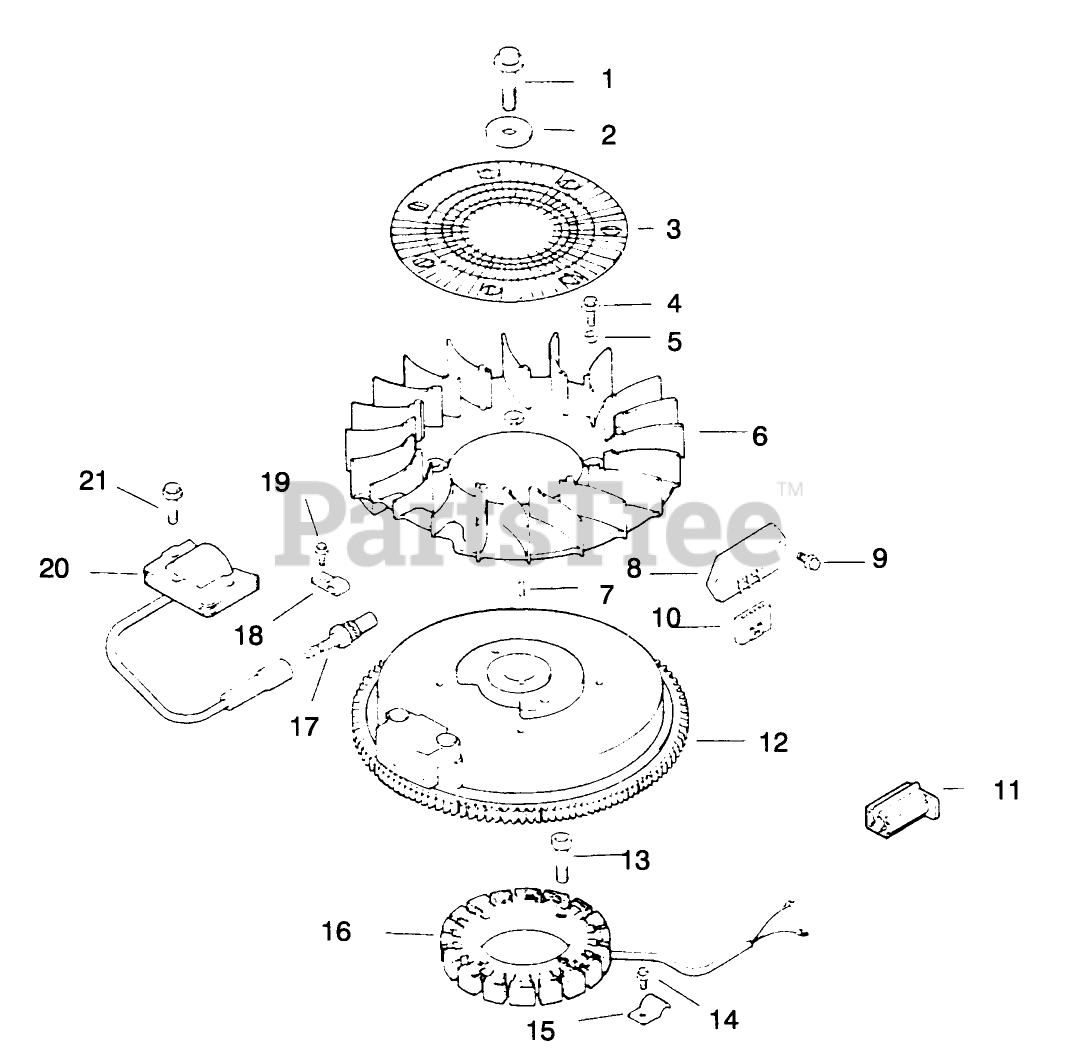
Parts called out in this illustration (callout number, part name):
1	Screw
2	Washer-Flat
3	Screen-Grass
5	Spacer-Fan
6	Fan (Only On: 72042, 72063, 72062, 72043)
8	Rectifier-Unrelated
10	Connector
11	Connector
12	Flywheel ASM (Only On: 72042, 72063, 72062, 72043)
15	Clip-Stator Harness (Only On: 72042, 72063, 72062, 72043)
16	Stator-15 amp
17	Spark Plug
20	Module-Ignition
